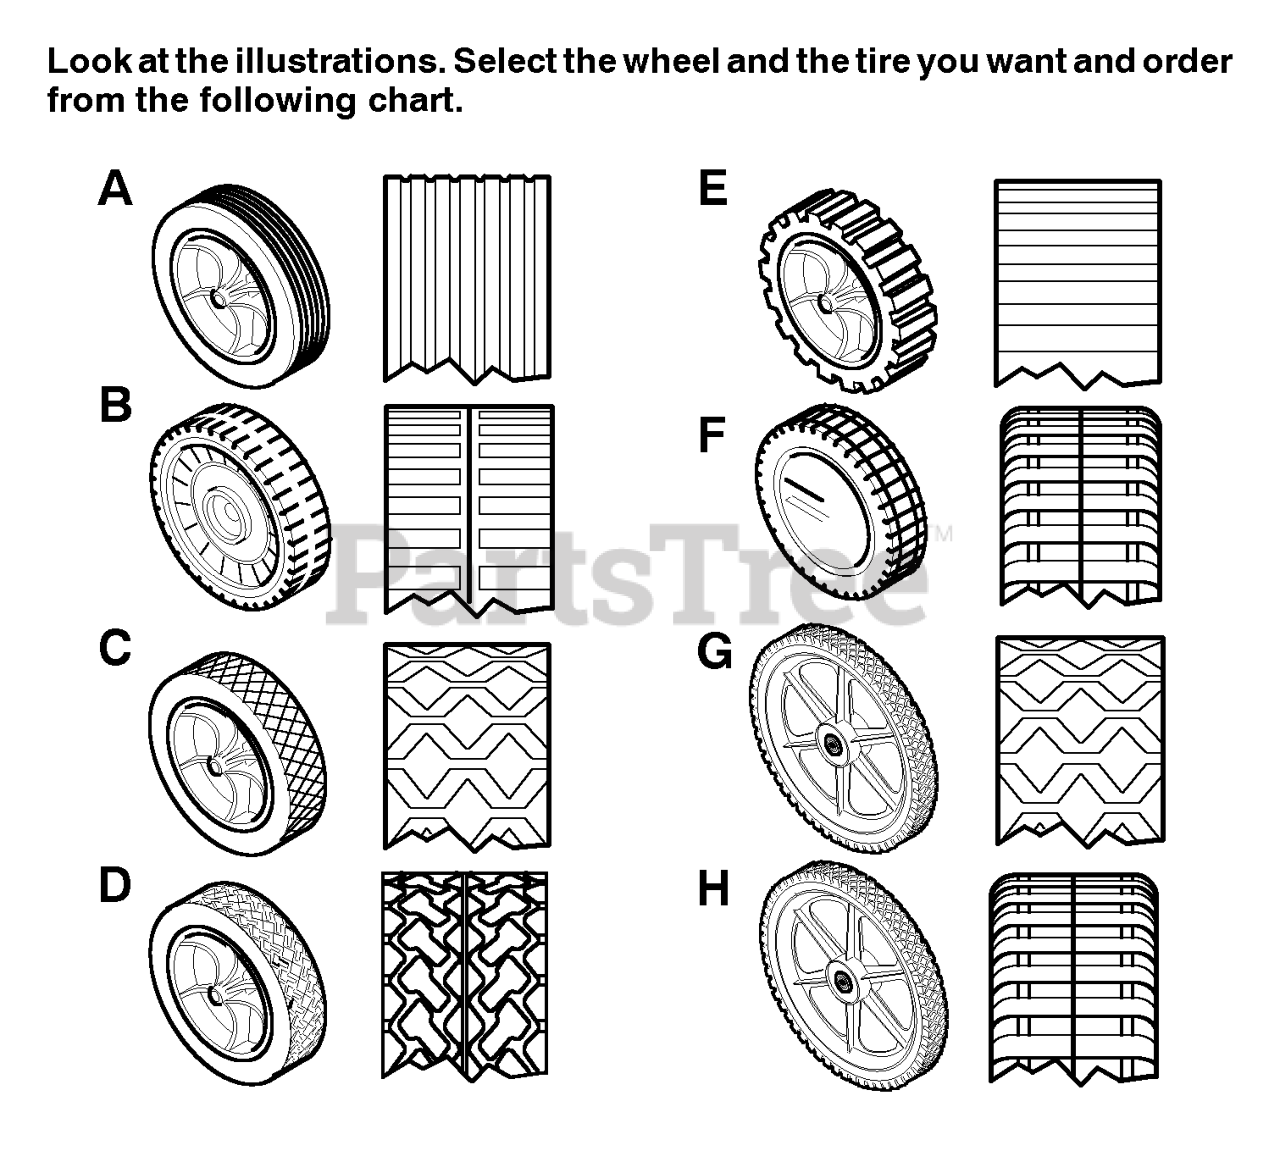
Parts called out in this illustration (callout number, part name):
A	WHEEL & TIRE ASSEMBLY, Light Gray, 8"
A	8-inch Plastic, Dark Gray
A	8-inch Metal, White
B	7-inch Plastic, White
B	7-inch Plastic, Light Gray
B	7-inch Plastic, Dark Gray
C	6-inch Plastic, White
C	7-inch Plastic, White
C	7-inch Plastic, Light Gray
C	7-inch Plastic, Dark Gray
C	8-inch Plastic, White
C	8-inch Plastic, Light Gray
C	8-inch Plastic, Dark Gray
C	8-inch Metal, White
D	7-inch Plastic, White
D	WHEEL & TIRE ASSEMBLY, White, 8"
D	8-inch Plastic, Light Gray
D	8-inch Plastic, Dark Gray
E	WHEEL & TIRE ASSEMBLY, White, 8"
E	8-inch Plastic, Dark Gray
E	8-inch Metal, White
F	WHEEL & TIRE ASSEMBLY, White, 8"
F	8-inch Plastic, Light Gray
F	8-inch Plastic, Dark Gray
F	8-inch Ball Bearing, Light Gray
F	8-inch Ball Bearing, Dark Gray
G	14-inch, White
G	14-inch, Light Gray
G	14-inch, Dark Gray
G	WHEEL & TIRE ASSEMBLY, White, 14"
G	14-in, Ball Bearing, Light Gray
G	14-in, Ball Bearing, Dark Gray
H	14-inch, White
H	14-inch, Light Gray
H	14-inch, Dark Gray
H	WHEEL & TIRE ASSEMBLY, Ball Bearing, 14"
H	14-in, Ball Bearing, Light Gray
H	14-in, Ball Bearing, Dark Gray
